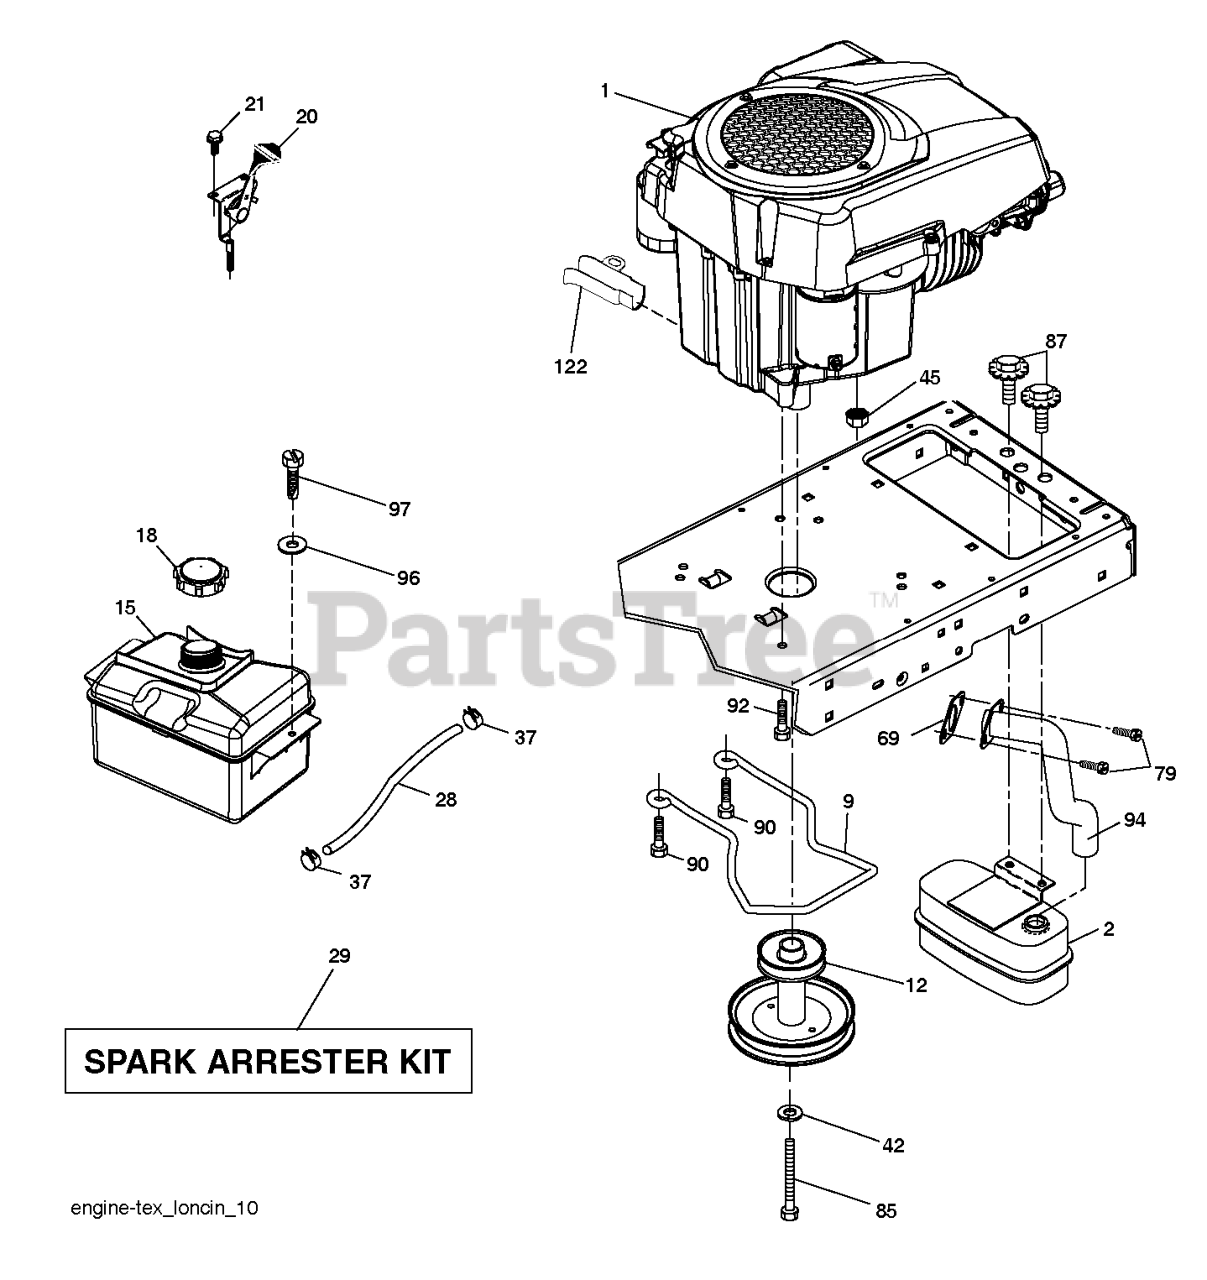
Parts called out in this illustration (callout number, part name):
1	ENGINE.LONCIN.SPARE/452
2	MUFFLER.ASM.SINGLE
9	KEEPER.BELT.ENG.4.25"2.BLT.431
12	ENGINE.PULLEY
15	FUEL.TANK.ASM.NON-EPA
18	CAP ASM.FUEL.2.25"FR.
20	CONTROL.TH/CK.C.
28	LINE.FUEL.20"FRONT.EMI
29	KIT.SPARK ARRESTOR 794945 B&S
37	HOSE CLAMP
45	NUT HEXAGON WITH FLANGE, SERRA
69	GASKET GASKET.EXHAUST.LONCIN 3
85	BOLT.HEX.7/16-20X4.GR5.1.5BLUE
87	BOLT.5/16-18UNCX3/4 W/SEMS.BLK
90	SCREW 3/8-16X1
92	SCREW 3/8-16X1
94	TUBE TUBE.EXHAUST.LONCIN 452.T
97	SCREW HEXWSHR 1/4-20X3/4
122	EXTENSION DRAIN OIL
